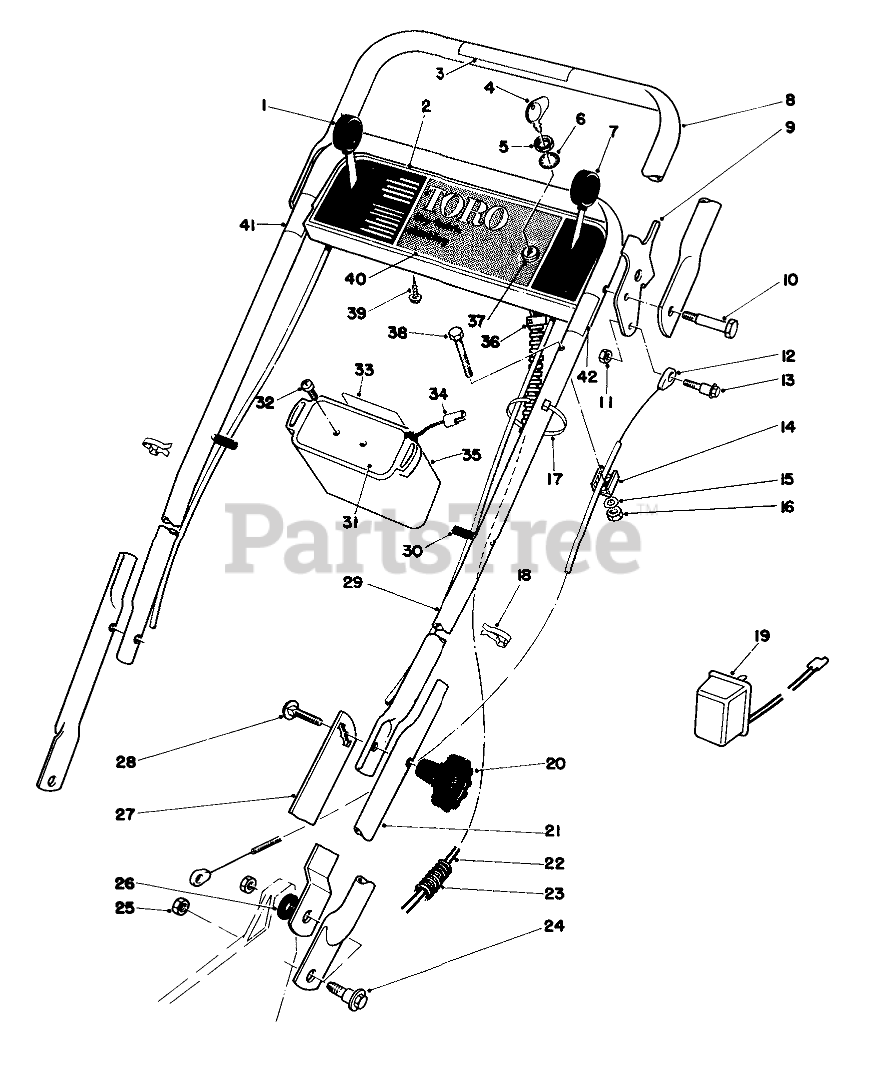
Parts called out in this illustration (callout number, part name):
1	GROUND SPEED CONTROL
2	CONTROL PLATE WA
3	Decal-Traction Handle (French & Dutch)
4	Key
5	NUT-HH
6	WASHER-TOOTH, INTERNAL
7	Throttle Control
8	Demand Handle
9	Demand Handle Stop
10	BOLT-SHOULDER
11	NUT-HEX, SIDE DEFORM
12	DEMAND HANDLE CABLE
13	Shoulder Bolt
14	CLAMP-CABLE
15	WASHER-FLAT
16	NUT-LOCK, NI
17	TIE-CABLE
18	BOWDEN CLIP
19	Charger
21	LOWER HANDLE
22	WIRE HARNESS
23	Cover-Wiring Harness
24	SCREW-SHOULDER
25	Nut
26	SPACER
27	Handle Latch L.H.
28	SCREW-CARR
29	Upper Handle
30	CAP-VINYL
31	BATTERY COVER
32	10-190X1/2 PAN HD SCR
33	Decal
34	Plug & Wire
35	Battery Case
36	RING FITTING
37	Starter Switch (Incl. Ref. #4-6)
38	SCREW-HH
39	SCREW-HWHTF
40	Decal-Key Lectric (French & Dutch)
41	Decal-Control Shift (French & Dutch)
42	Decal Throttle Control
